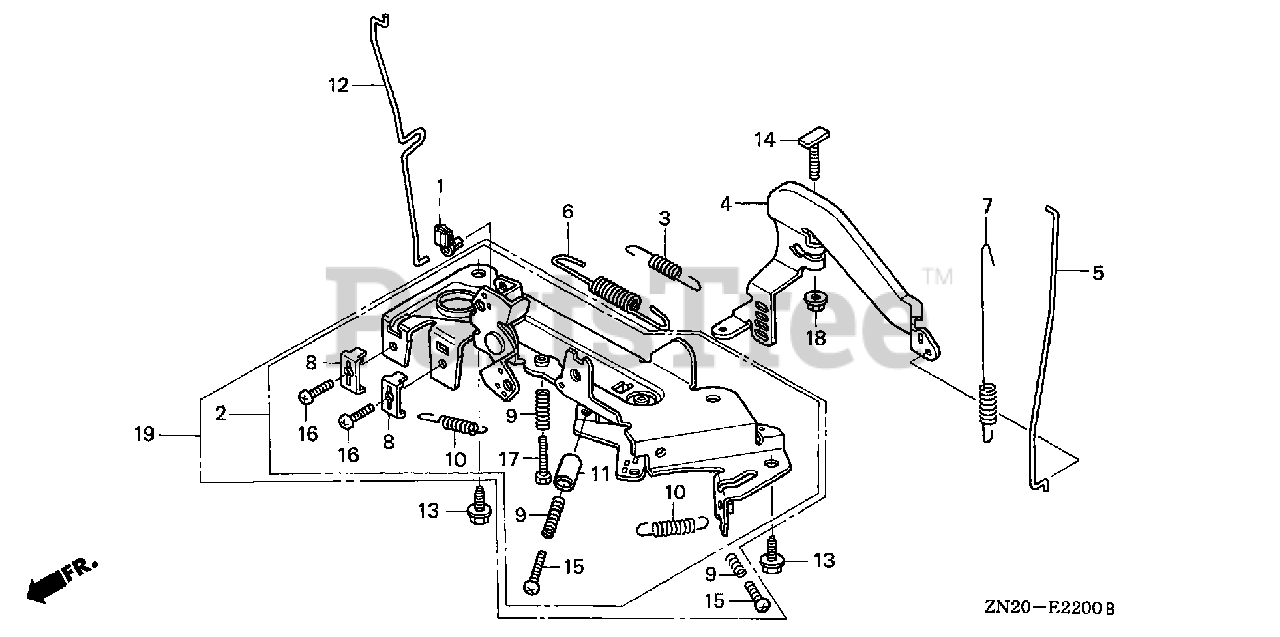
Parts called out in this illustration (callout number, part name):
1	JOINT, ROD
3	SPRING, STARTER
4	ARM, GOVERNOR
5	ROD, GOVERNOR
6	SPRING, GOVERNOR
7	SPRING, THROTTLE RETURN
8	HOLDER, CABLE
9	SPRING, CONTROL ADJUSTING
10	SPRING, CABLE RETURN
12	ROD, CHOKE CONTROL
13	BOLT, FLANGE (6X14) (CT200)
14	BOLT, GOVERNOR ARM
15	SCREW, PAN (5X35)
16	BOLT, RECESSED (5X16)
17	BOLT, RECESSED (5X25)
18	NUT, FLANGE (6MM)
19	CONTROL ASSY.
